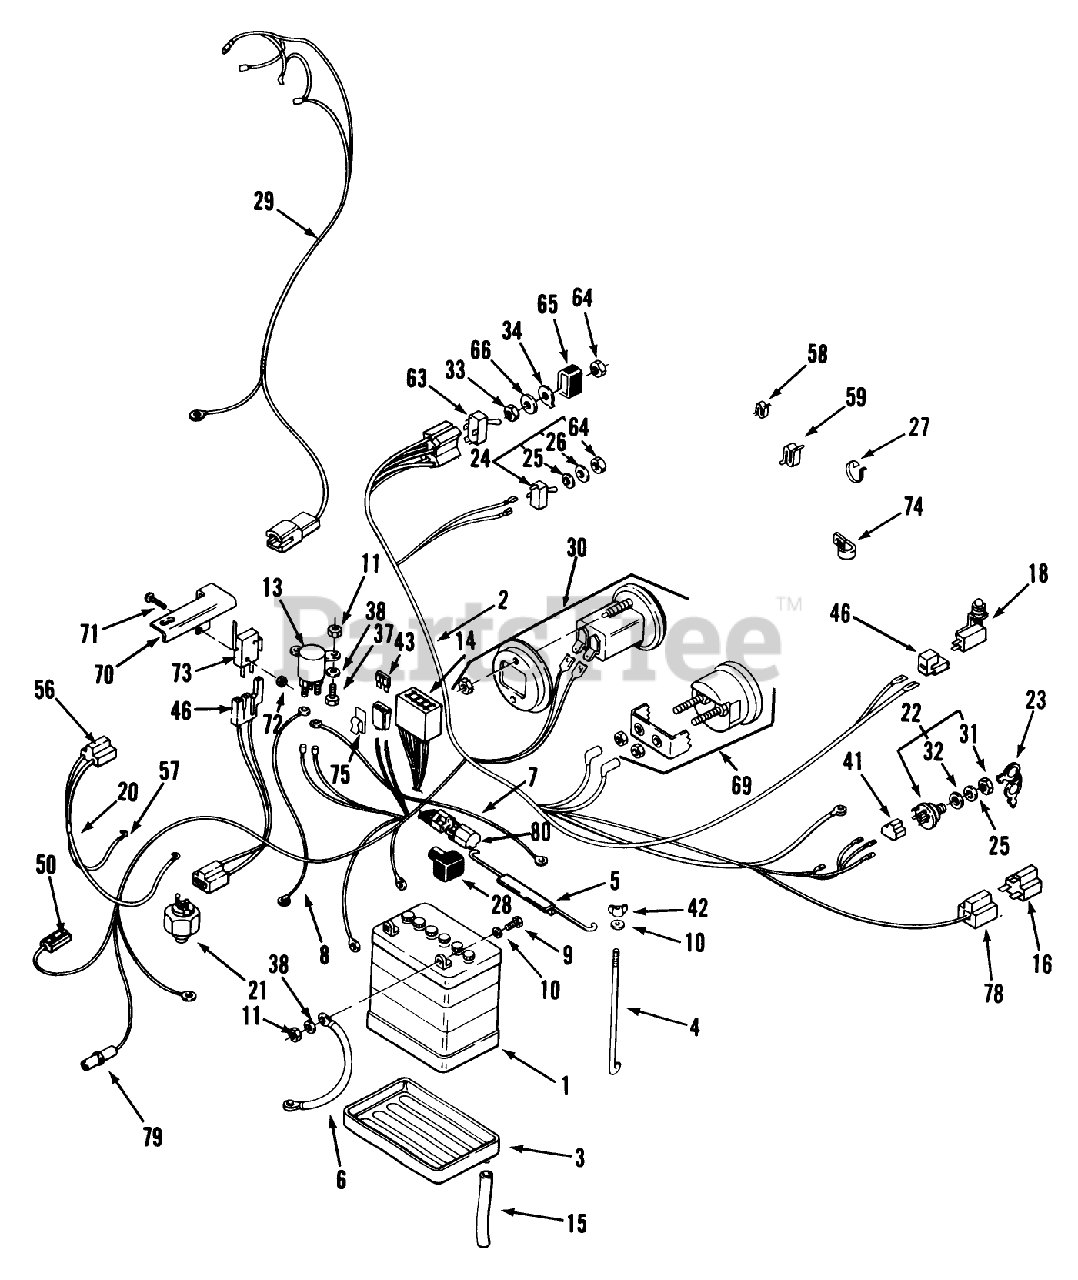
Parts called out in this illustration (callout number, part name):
3	TRAY-BATTERY
5	ROD-BATTERY HOLD DWN
6	WIRE -BLACK
7	WIRE - 14" BLACK
15	TUBE-BATTERY DRAIN
20	ASSY WIRING HARNESS
21	SWITCH (N.C.-TRANS)
24	SWITCH-LIGHTS
26	Washer
30	GAUGE-HOURMETER
34	TAB-WASHER
43	FUSE-BLADE, 15 AMP
46	CONNECTOR BODY
50	CONNECTOR BODY ELECT
56	CONNECTOR BODY *B
57	TERMINAL-TAB RCPT
58	CLIP
63	SWITCH-TOGGLE DPDT
64	*DISC**
65	COVER-PTO SWITCH
66	WASHER-FLAT
73	SWITCH
74	CLAMP
78	CONNECTOR 5 WAY
80	RELAY
